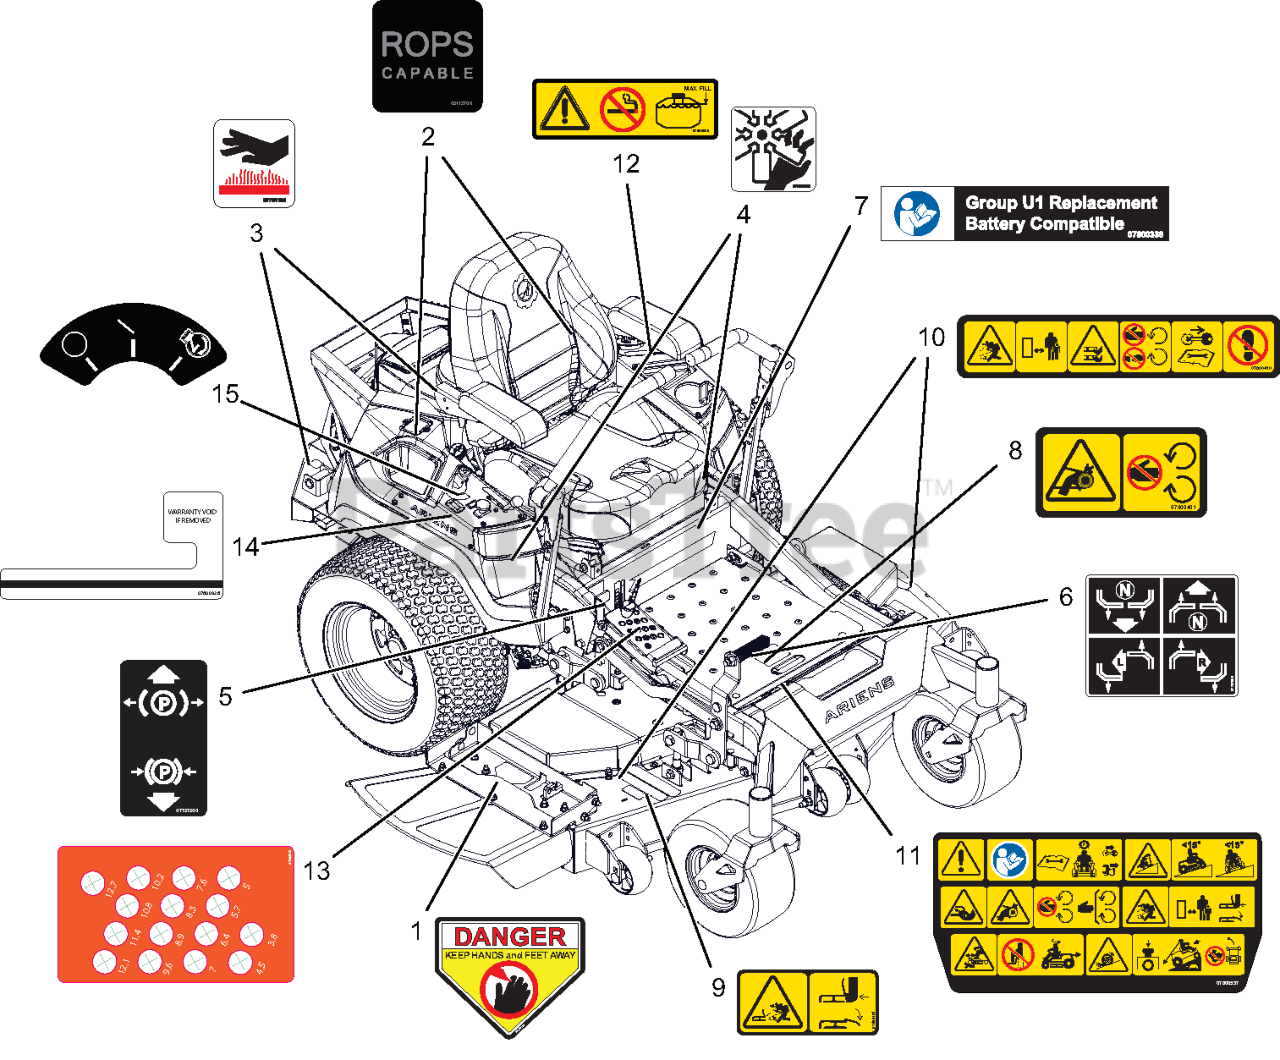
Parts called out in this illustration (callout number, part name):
1	DECAL, DANGER
2	DECAL, ROPS LOCATION
3	DECAL, HOT SURFACE
4	DECAL, DANGER FAN
5	DECAL, PARKING BRAKE LEVER
6	DECAL, INSTRUCTIONAL-STEERING
7	DECAL, U1 BATTERY REPLACEMENT
8	DECAL, SAFETY - GUARDING
9	DECAL, SAFETY - DECK GUARDING
10	DECAL, DECK SAFETY
11	DECAL, MAIN SAFETY
12	DECAL, FUEL WARNING
13	DECAL, APEX HOC METRIC
14	DECAL,HOURMETER - SECURITY
15	DECAL, KEYSWITCH
